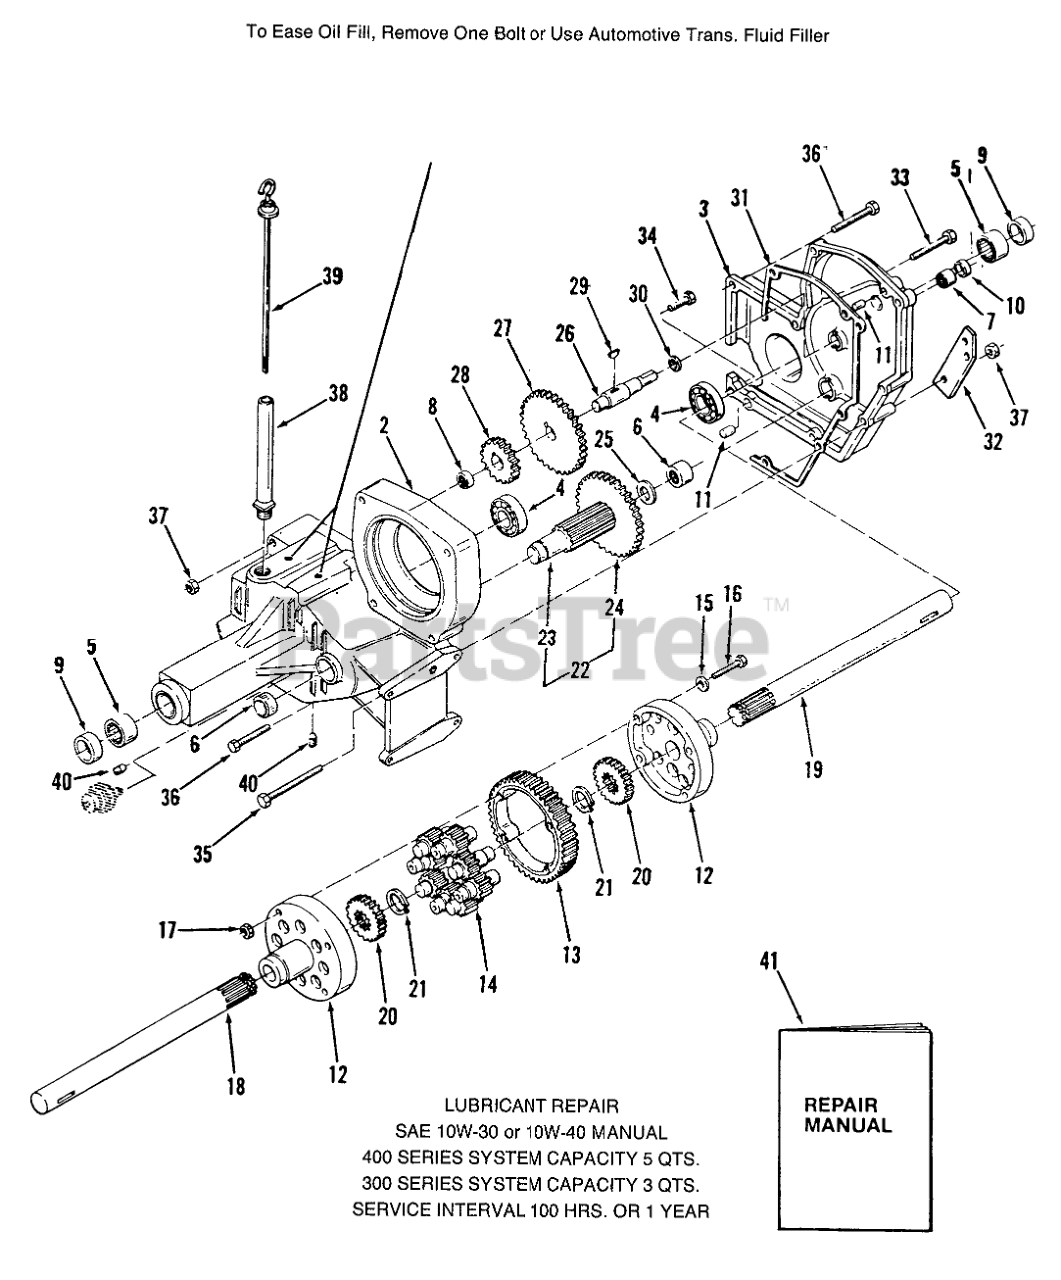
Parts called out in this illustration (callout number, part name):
2	CASE-TRANS RH
3	CASE TRANS LH
4	BEARING-BALL
5	BEARING
6	BEARING-NEEDLE
7	NEEDLE BEARING
8	BEARING-NEEDLE
9	SEAL-OIL
10	Seal
11	PIN-LOCATING
12	END CAP-DIFFERENTIAL
13	GEAR-DIFFERENTIAL RING, 43T
14	GEAR-PINION, 11T
15	WASHER
16	BOLT-HEX
18	AXLE-REAR RH
19	AXLE-REAR LH
20	GEAR-AXLE DIFFERENTIAL
21	RING-SNAP
22	ASSY GEAR
23	PINION SHAFT
24	GEAR 46T
25	WASHER-THRUST
26	SHAFT GEAR
27	GEAR 46 TEETH
28	GEAR 20 TEETH
29	Key
30	Race Thrust
31	GASKET-TRANSMISSION
32	BRACKET-BRAKEB
33	Bolt
34	Bolt
35	Hex Bolt
36	HHCS
37	NUT
38	NIPPLE-TRANS FILL
39	Dipstick
40	PLUG 1/4 PIPE ALLEN
41	Repair Manual
